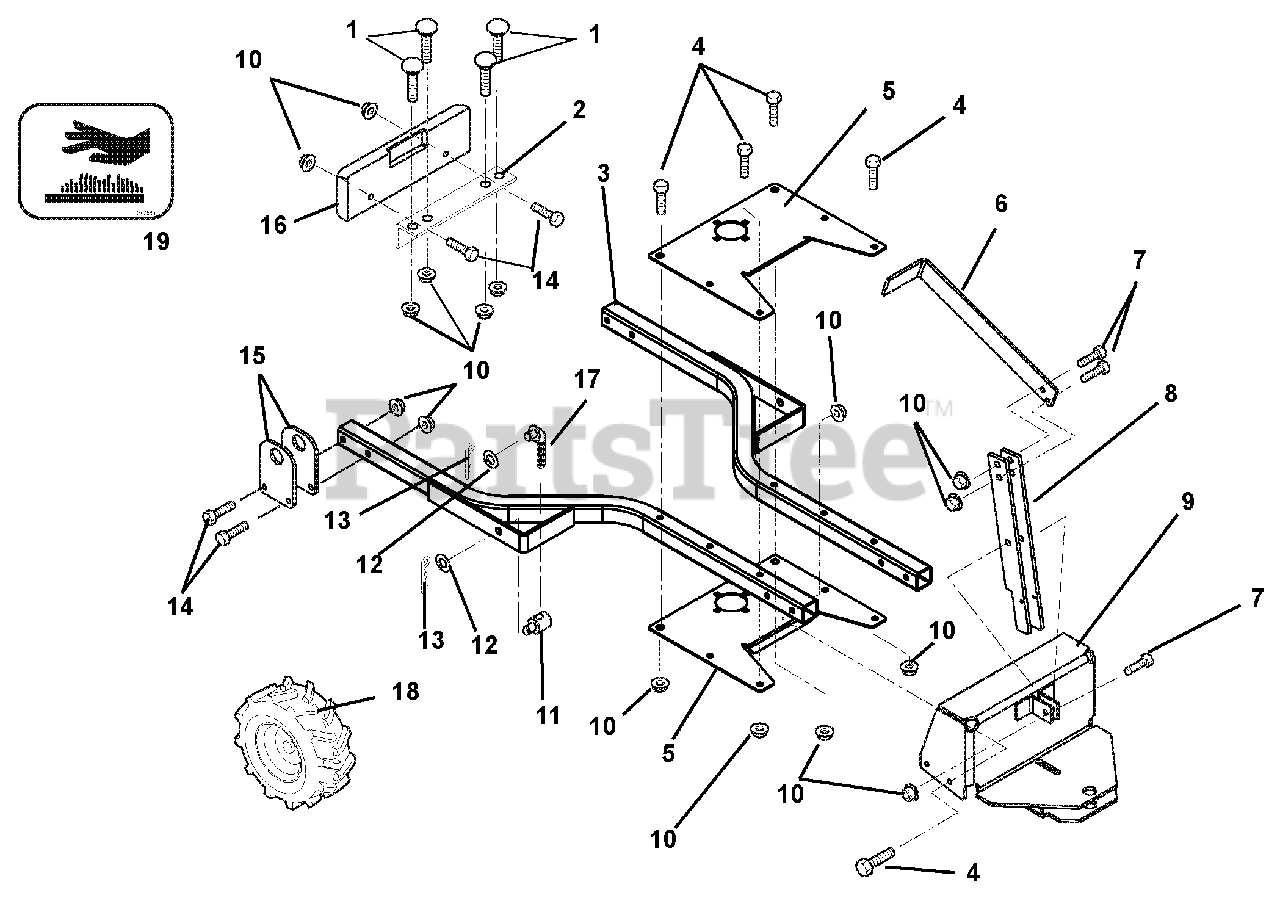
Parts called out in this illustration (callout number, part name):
1	@BLT-RDHDSQNK .38-16X2.50 G5YZ
2	BRKT,ANGLE
3	WMT,SUB-FRAME TUBE
4	@BLT-HEX .38-16X2.25 GR5 YWZC
5	PLATE,SUB-FRAME
7	@BLT-HEX .38-16X1.25 GR5 YWZC
9	YOKE,BLADE MOUNT
10	@NUT-LK-TOP-FLG .38-16 YWZC
11	TRUNNION-.50
12	WSHR-FL-STL .531X1.250X.10 YWZ
13	PIN, HAIR, EXT - #16 YWZC
14	@BLT-HEX .38-16X2.50 GR5 YWZC
15	BRKT,PIVOT
16	WEIGHT, CAST IRON
17	LINK, LIFT
18	ASSY,WHEEL & TIRE 18X6.5 S-HOG
19	DECAL, HOT SURFACE
